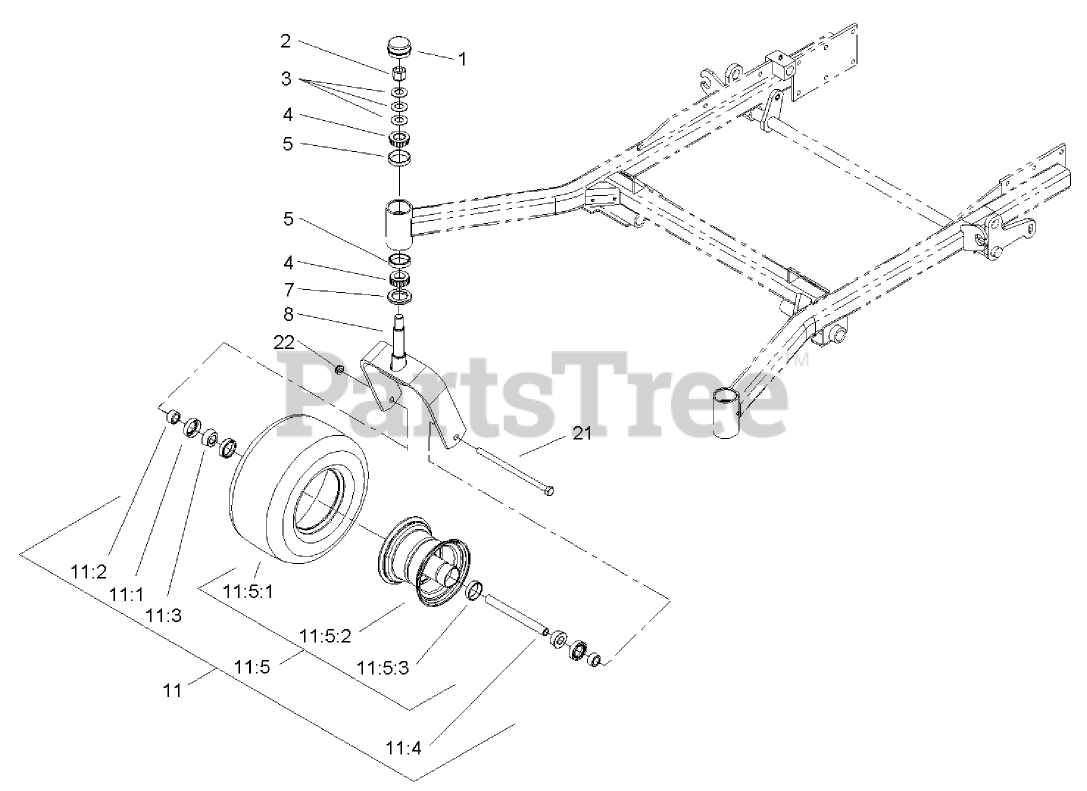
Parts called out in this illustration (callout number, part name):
1	CAP-GREASE
2	NUT-LOCK, NI
3	WASHER-BELLVILLE
4	BEARING-CONE, TAPERED
5	BEARING-CUP, TAPERED
7	SEAL-GREASE
8	CASTER
11	CASTER WHEEL ASM
11:1	SEAL-BEARING
11:2	SPACER-BEARING
11:3	BEARING-CONE, TAPER
11:4	SPACER-CASTER, FRONT
11:5	WHEEL AND TIRE ASM
11:5:3	BEARING-CUP
21	SCREW-HH
22	NUT-LOCK, NI
